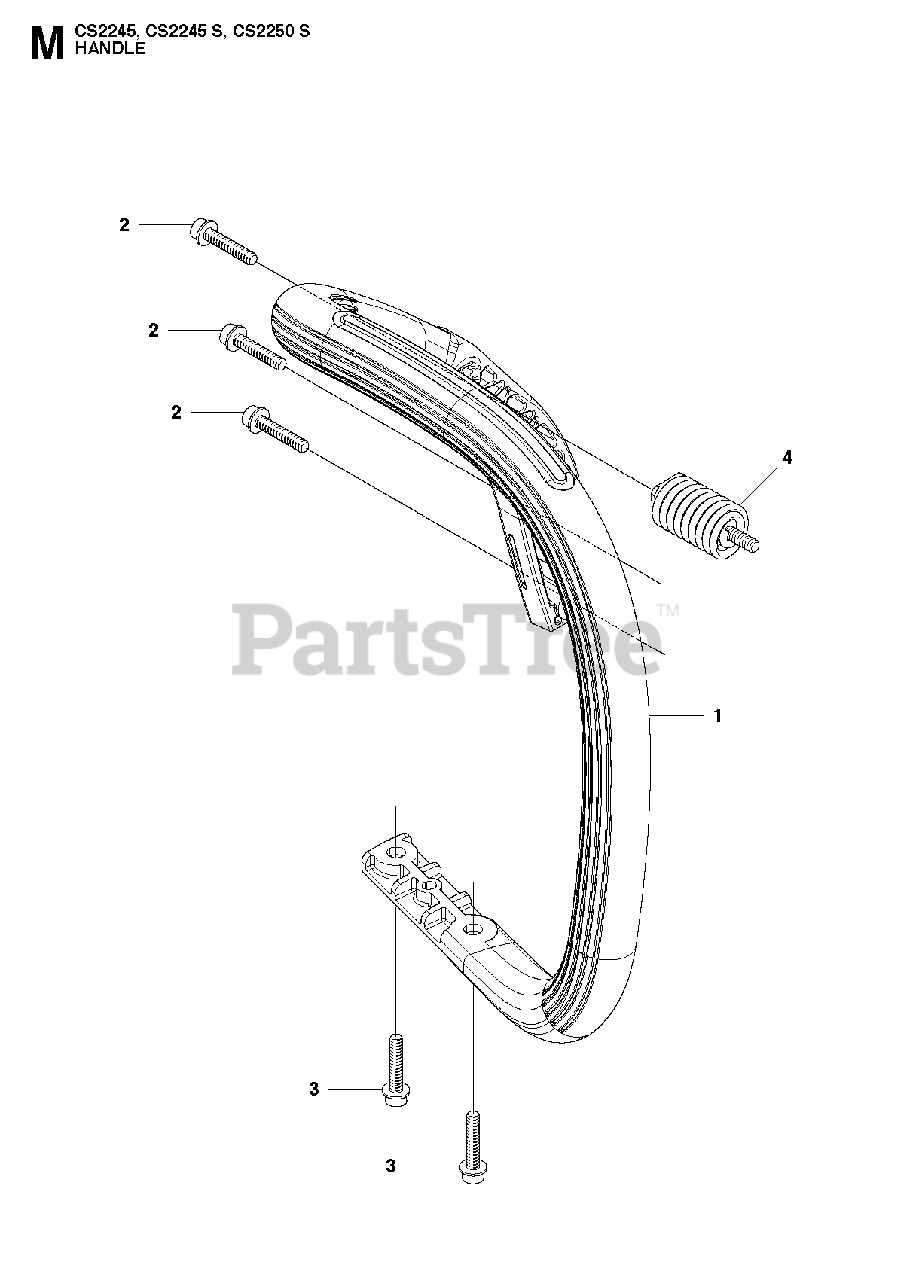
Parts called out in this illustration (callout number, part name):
1	FRONT HANDLE
2	SCREW IHSCFT
4	INSULATOR
